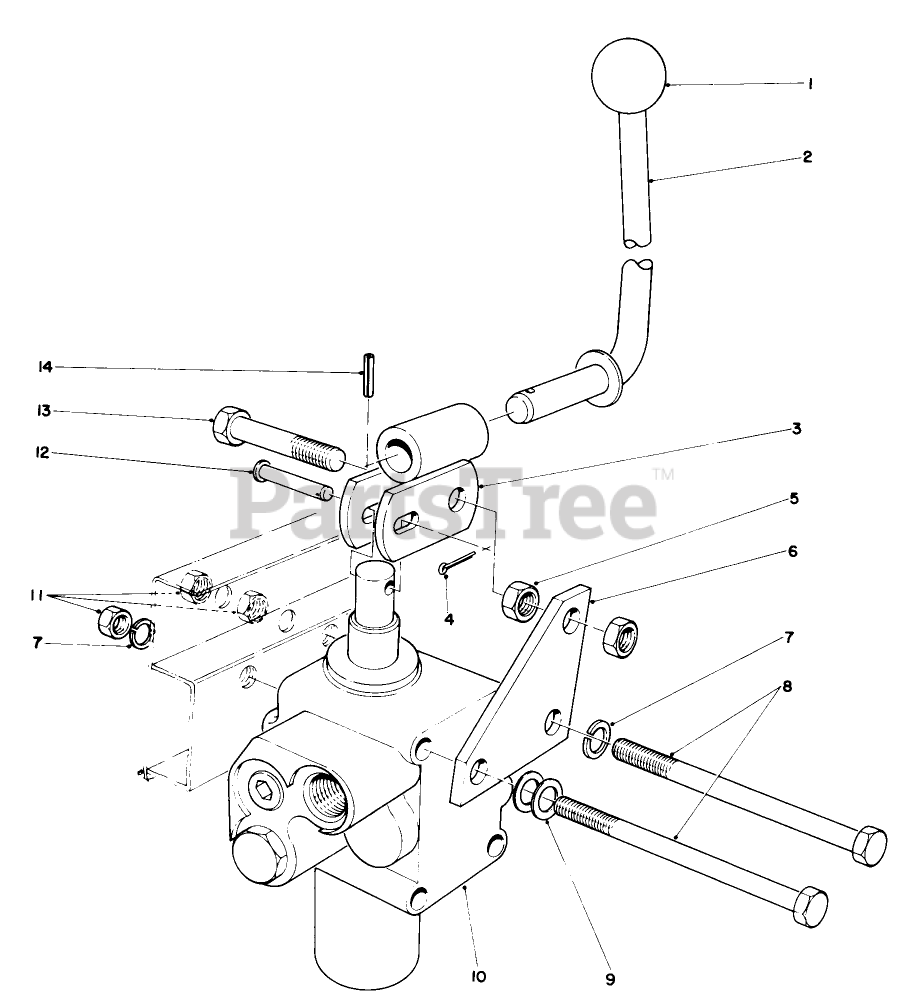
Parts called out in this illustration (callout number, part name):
1	KNOB-CONTROL
2	Lever-Valve
3	Valve Lever Link
4	PIN-COTTER
5	NUT-JAM
6	Wheel Bolt
7	WASHER-LOCK
8	SCREW-HH
9	WASHER-FLAT
10	VALVE ASM
11	NUT-HEX
12	PIN-CLEVIS
13	SCREW-HH
14	PIN-ROLL
